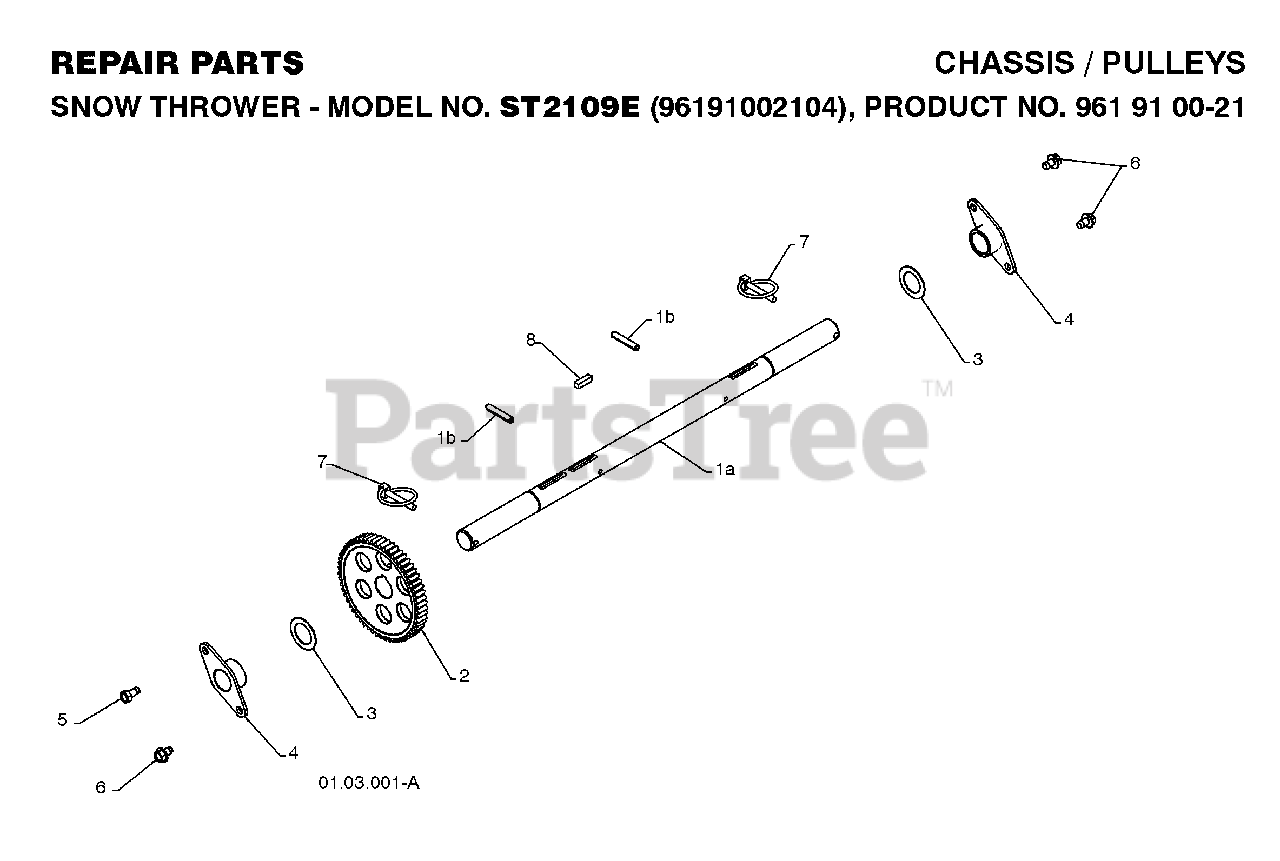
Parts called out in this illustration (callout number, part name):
1A	SHAFT.AXLE.POWER.STEERING
1B	PIN.ROLL.3/16
2	GEAR, AXLE (58T)
3	WASHER TRUST 1"
4	BEARING, AXLE
7	PIN KLIK, 1/4
8	KEY, SQUARE 1/4 X .875
